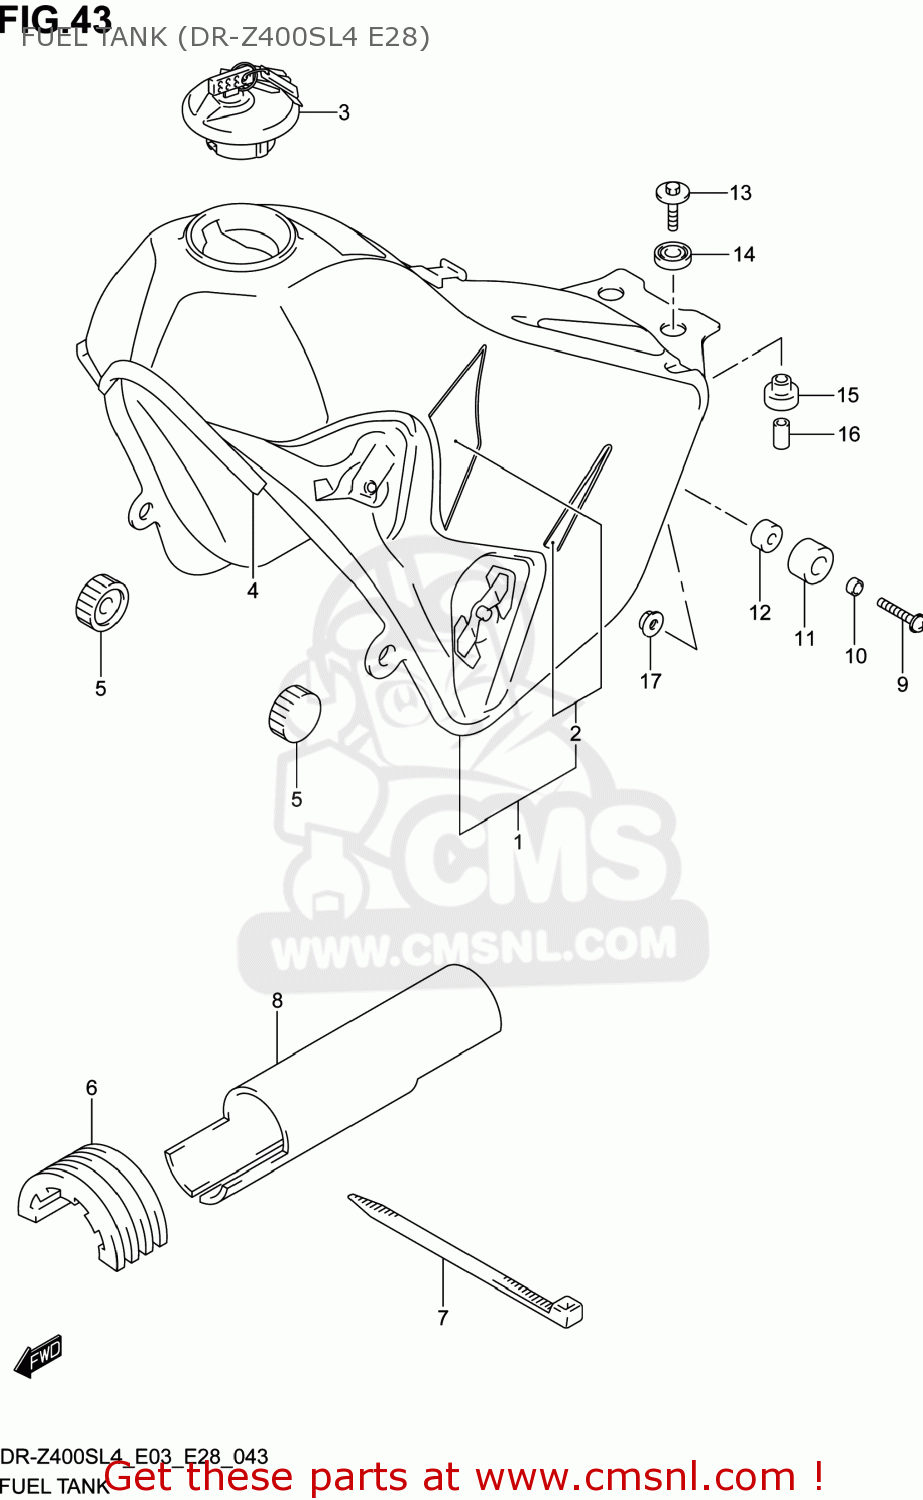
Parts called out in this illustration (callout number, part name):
1	TANK ASSY,FUEL(BLACK)
2	TAPE SET,FUEL TANK
3	CAP SET,FUEL TANK
4	MOLDING
5	CUSHION
6	CUSHION,FUEL TANK
7	CLAMP(L:300)
8	SHIELD,FUEL TANK
9	SCREW
10	SPACER(6.5X20X9)
11	CUSHION
12	SPACER(6.5X9X5)
13	BOLT(6X30)
14	CUSHION
15	CUSHION
16	SPACER(6.5X9X18)
17	NUT
